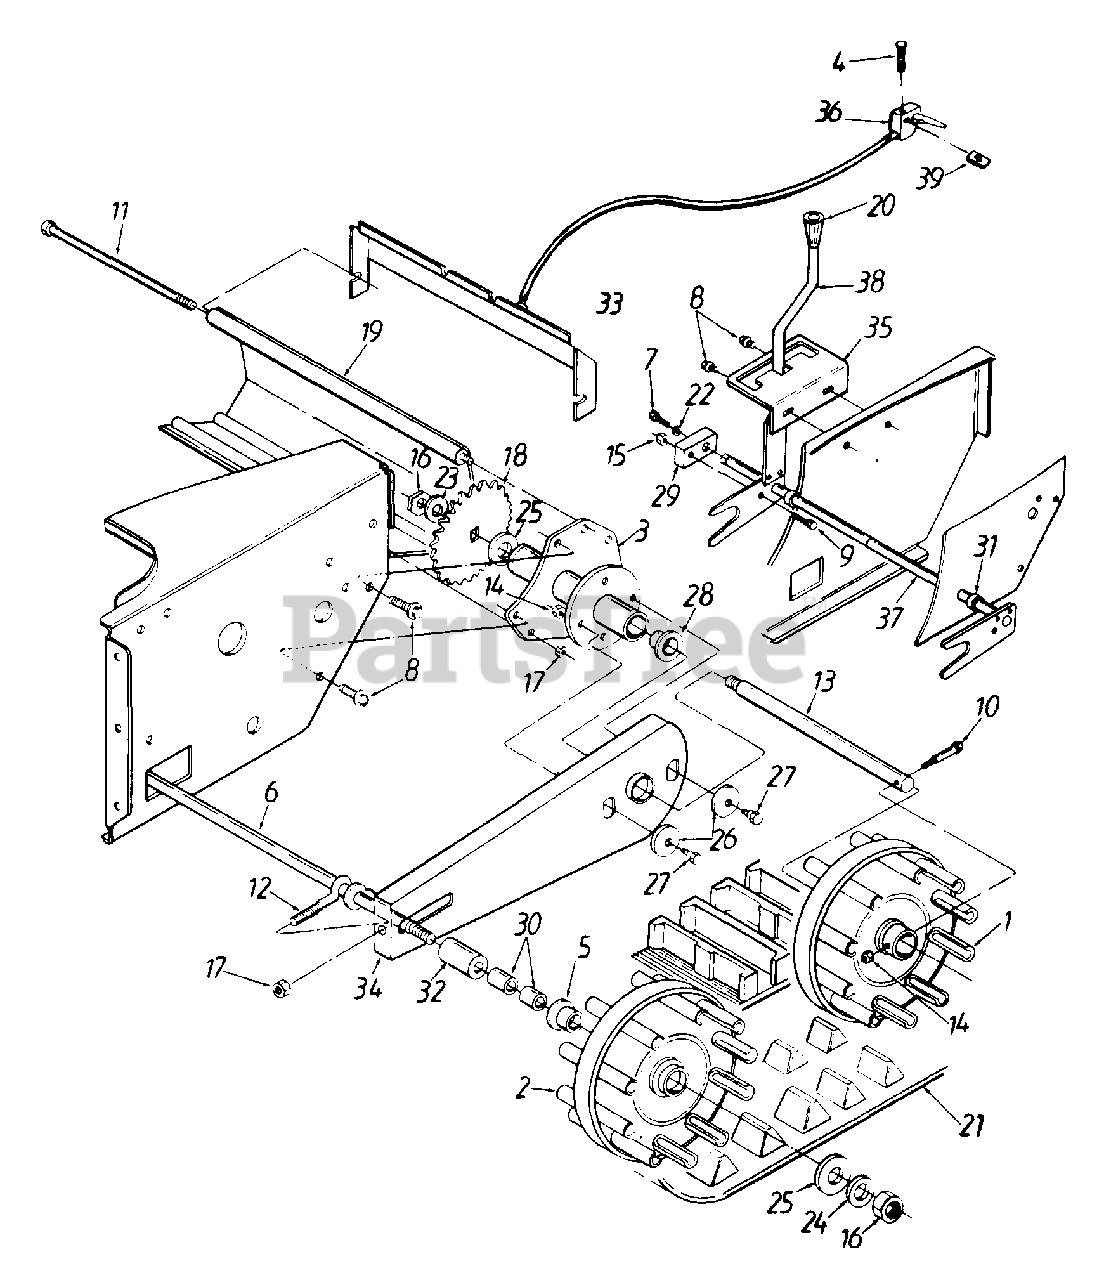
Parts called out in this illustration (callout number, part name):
1	Drive Wheel Ass'y.
2	Idler Wheel Ass'y.
3	Track Hub Ass'y.
4	Oval C-Sunk Hd. Scr. 10-24 x 1.375" Lg.
5	Flange Bearing 3/4" I.D. x 15/16"
7	Hex Bolt 5/16-24 x .75" Lg.
8	Hex Wash. TT-Tap Scr. 5/16-18 x .62" Lg.
9	Hex Bolt 5/16-24 x .75" Lg. (Special)
10	Bolt 5/16-18 x 1.5" Lg.
11	Hex Bolt Ass'y. 5/16-18 x 9.81"
12	Eyebolt 5/16-18 x 3" Lg.
13	Drive Axle
14	Hex Cent. L-Nut 5/16-18 Thd.
15	Hex Cent. L-Nut 5/16-24 Thd.
16	Hex Ins. Jam L-Nut 1/2-20 Thd.
17	Hex L-Nut 5/16-18 Thd.
18	24 Tooth Sprocket
19	Track Housing
21	Snow Track
22	L-Wash. 5/16" I.D.
23	Bell-Wash. .515" I.D. x 1.14"
25	Fl-Wash. .793" I.D. x 1.24" O.D.
26	Fl-Wash. 3/8" I.D. x 7/16" O.D.
27	Shld. Bolt .437" Dia. x .162
28	Flange Bearing 3/4" I.D. x 15/16"
29	Lift Shaft Drive
30	Spacer .5" I.D. x .78" Lg.
31	Spacer .628" I.D. x .5" Lg.
32	Spacer .51" I.D. x 1.34" Lg.
36	Track Steer Cable w/Trigger
39	Flat Weld Nut #10-24 Thd.
